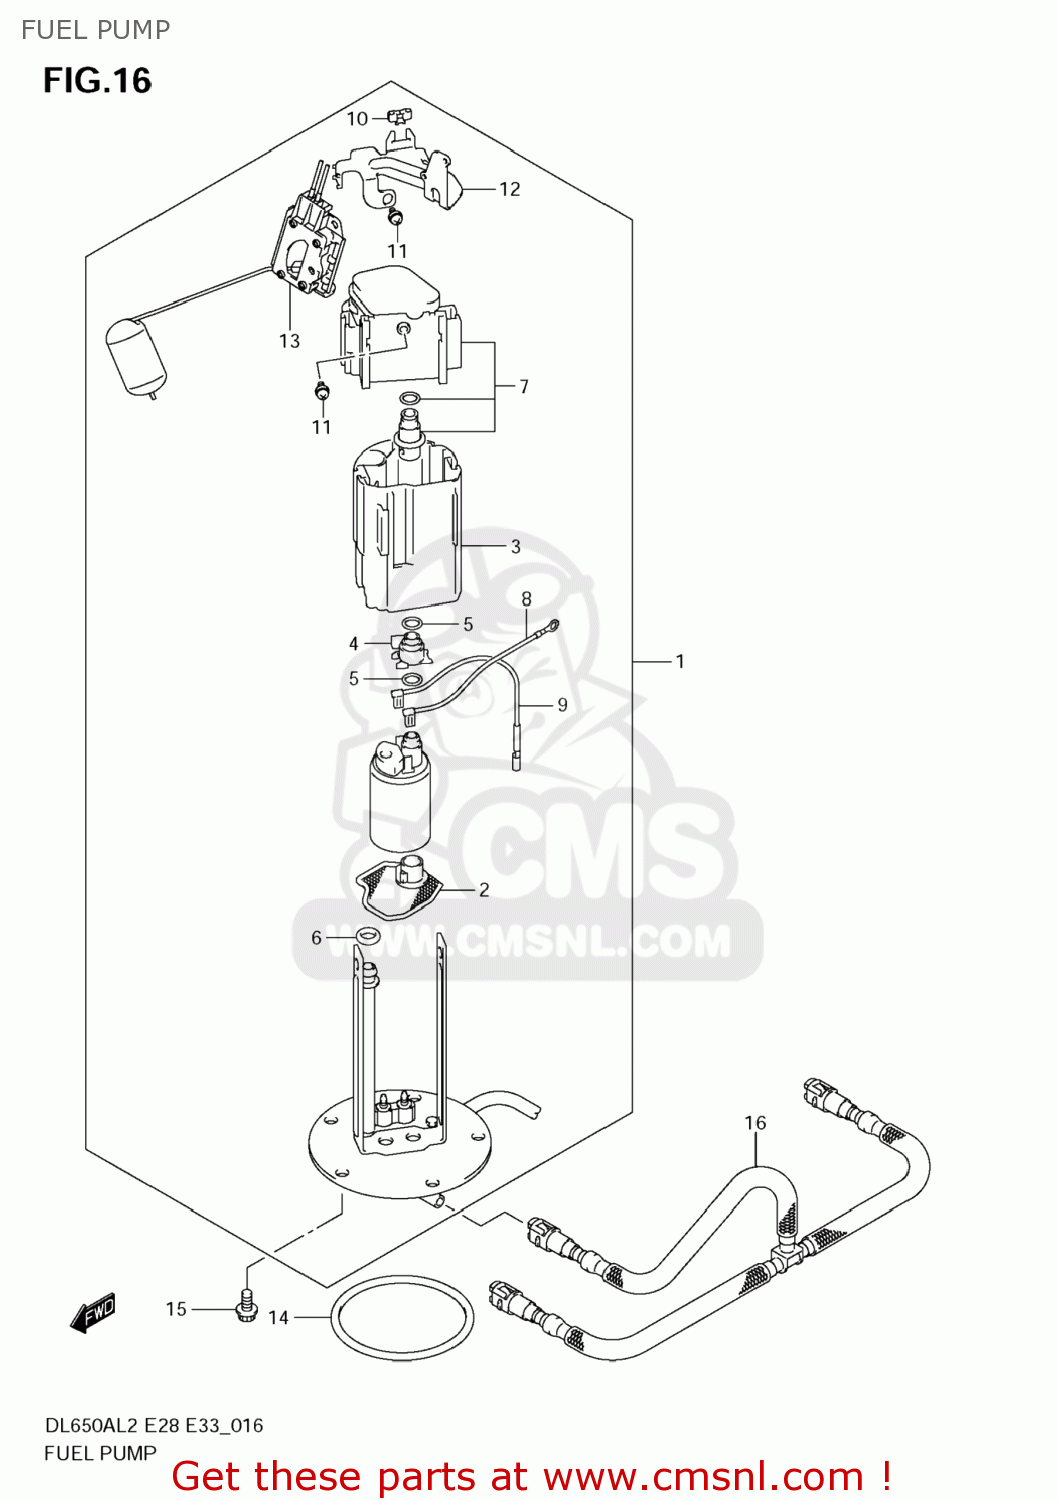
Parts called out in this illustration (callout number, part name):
1	PUMP ASSY,FUEL
2	STRAINER
3	CUP
4	JOINT
5	O RING
6	O RING
7	REGULATOR,FUEL
8	WIRE,EARTH
9	WIRE,LEAD
10	SADDLE,EDGE
11	SCREW
12	BRACKET,FUEL GAUGE
13	GAUGE ASSY,FUEL LEVEL SENDER
14	O RING,FUEL PUMP
15	BOLT
16	HOSE,FUEL
